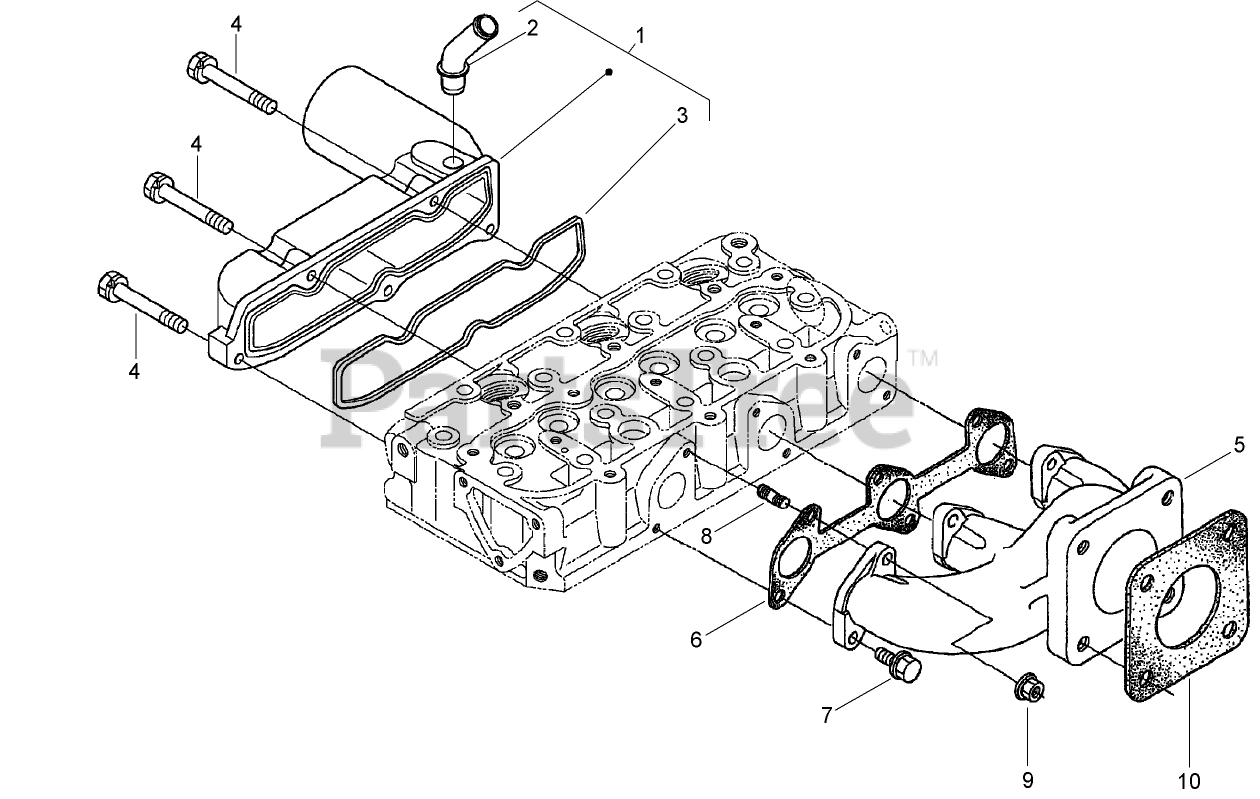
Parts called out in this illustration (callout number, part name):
1	INLET MANIFOLD ASM
2	PIPE-BREATHER
3	GASKET-MANIFOLD, INTAKE
5	MANIFOLD-EXHAUST
6	GASKET-MANIFOLD, EXHAUST
10	GASKET-MUFFLER
